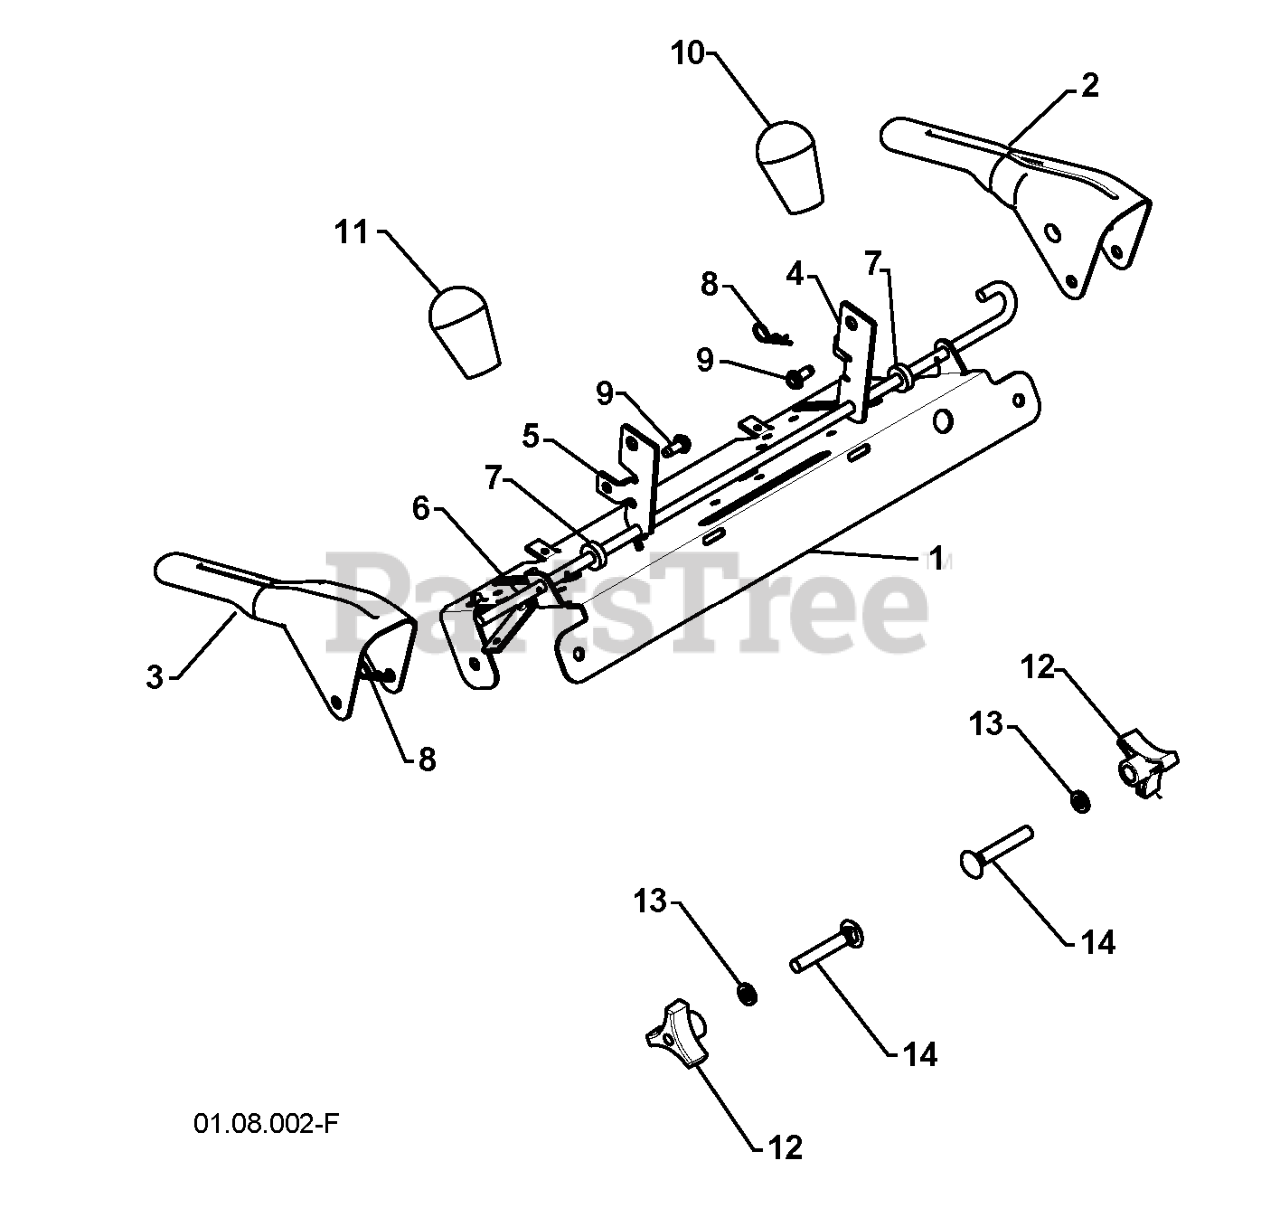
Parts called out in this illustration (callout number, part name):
1	PANEL.CONTROL.PNT.BLACK
2	RP.LEVER.CONTROL.LH.BLACK
3	CONTROLLEVERRH
4	ARM.TRACTION.ROD.YZ
5	ARM.IMPELLER.ROD.SNOW
6	BAIL.CONTROL.INTERLOCK
7	SPACER.CONTROL.LEVER
8	SPRING RETAINER
9	SCREW 14-20 X 5/8
10	KNOB LEVER, BLACK
11	RED KNOB SHIFTER
12	KNOB.HANDLE.3/8.TRI-POINT.BLAC
13	WASHER
14	BOLT 3/8-16 X 2-1/4
